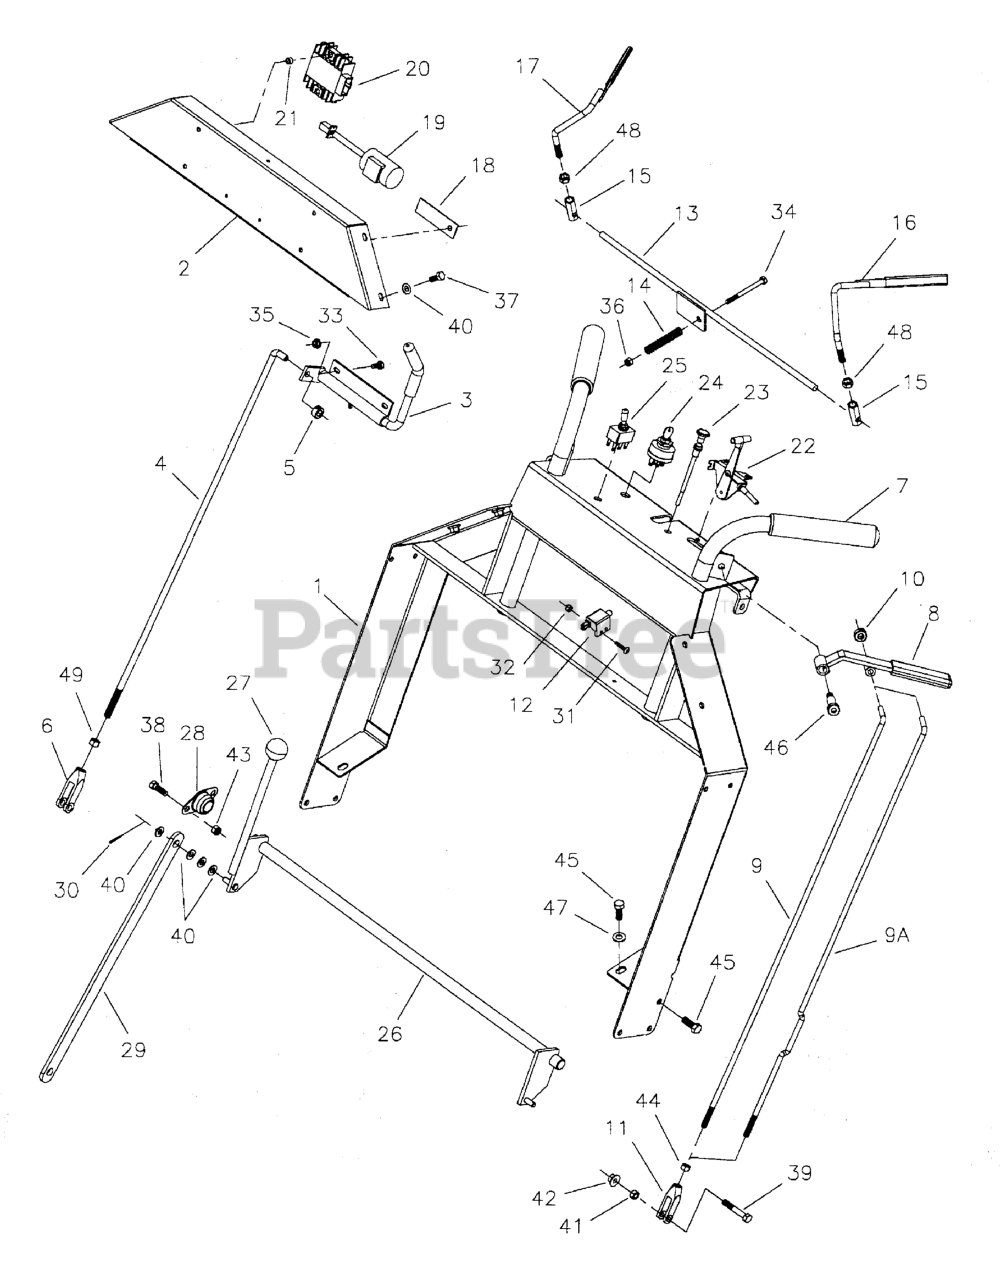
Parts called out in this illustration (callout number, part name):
1	DDS HANDLE BAR WELDMENT
2	COVER, Handle Bar
3	LEVER, Control
3	GRIP, Foam
4	ROD, Forward Control
5	COLLAR, 3/8" Set
6	CLEVIS, 3/8-24, Plastic
7	GRIP, Foam
8	ASSM, HANDLE CONTROLS - RED
8	GRIP, FOAM, 1/4 X 1 X 4.1
9	ROD, Reverse Control
9A	ROD, DDSKAV23 Reverse-Left
10	COLLAR, 5/16" Set
11	CLEVIS, 5/16-24, Plastic
12	SWITCH, PLUNGER, N.C.
13	SWITCH ROD
14	SPRING, Compression
15	HEX ADJUSTER
16	ASSM, OPERATOR PRESENCE, LH
16	GRIP, Vinyl
17	ASSM, OPERATOR PRESENCE, RH
18	Condenser Hold Down
21	SPACER, .25 X .37 X .25
22	CABLE, Throttle, 31"
22	CABLE, Throttle, 54"
23	CABLE, CHOKE CONTROL, 45
23	CABLE, CHOKE CONTROL, 27.5"
24	SWITCH, IGNITION, 6 POST
24	SWITCH, Ignition, Complete
25	SWITCH, Electric Clutch
25	SWITCH, BLADE ENGAGEMENT
26	SHAFT, Brake Handle
27	KNOB
28	BEARING, Flange
29	Brake Push Rod
30	PIN, 3/32 X 0.750, COT, ZINC/CLEAR
31	SCREW, #10-24 X 1 RS, CZ
32	NUT, #10-24 Hex Nylon Lock
33	HHCS, 1/4-20 X 0.625, GR5, ZINC/CLEAR
34	BOLT, 1/4-20 x 3
35	NUT, 1/4-20 HEX SERR. FLANGE
36	NUT, 1/4-20 HEX NYLON LOCK
37	BOLT, 5/16-18 X 3/4 GD5
38	BOLT, 5/16-18 X 1 GD5 YZ
39	BOLT, 5/16-18 X 2
40	WASHER, 5/16" SAE
41	NUT, 5/16-18 HEX
42	NUT, 5/16-18 HEX SERRATED FLANGE (LARGE)
43	NUT, 5/16-18 Hex Nylon Lock
44	NUT, 5/16-24 Hex
45	BOLT, 3/8-16 X 1" GD5 CZ
46	SHOULDER BOLT, 1/2 x 1-1/2
47	WASHER, 3/8 SAE
48	NUT, 3/8-16 Hex
49	NUT, 3/8-24 Hex
